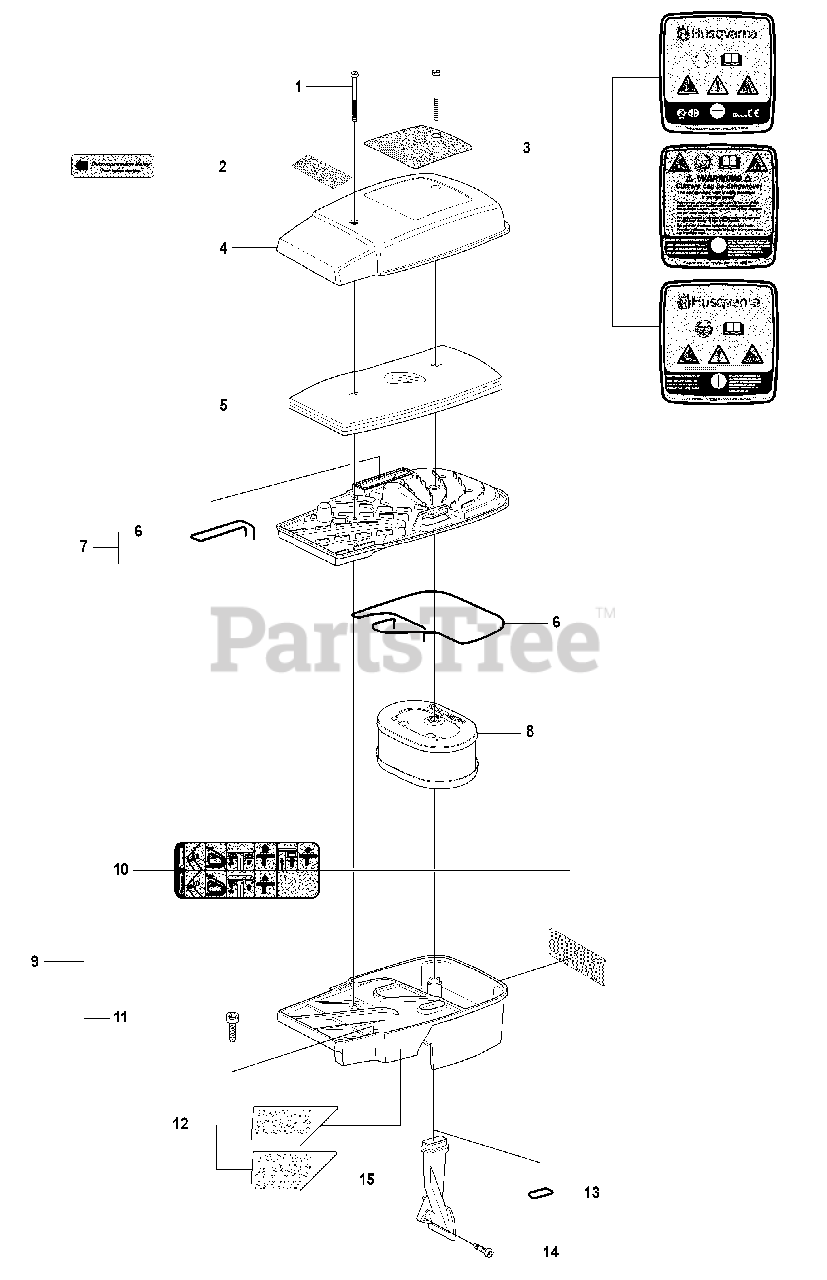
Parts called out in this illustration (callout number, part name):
3	LABEL
4	AIR FILTER COVER
7	FILTER BOTTOM
8	AIR FILTER
9	CYLINDER COVER ASSY
12	LABEL
15	AIR NOZZLE
